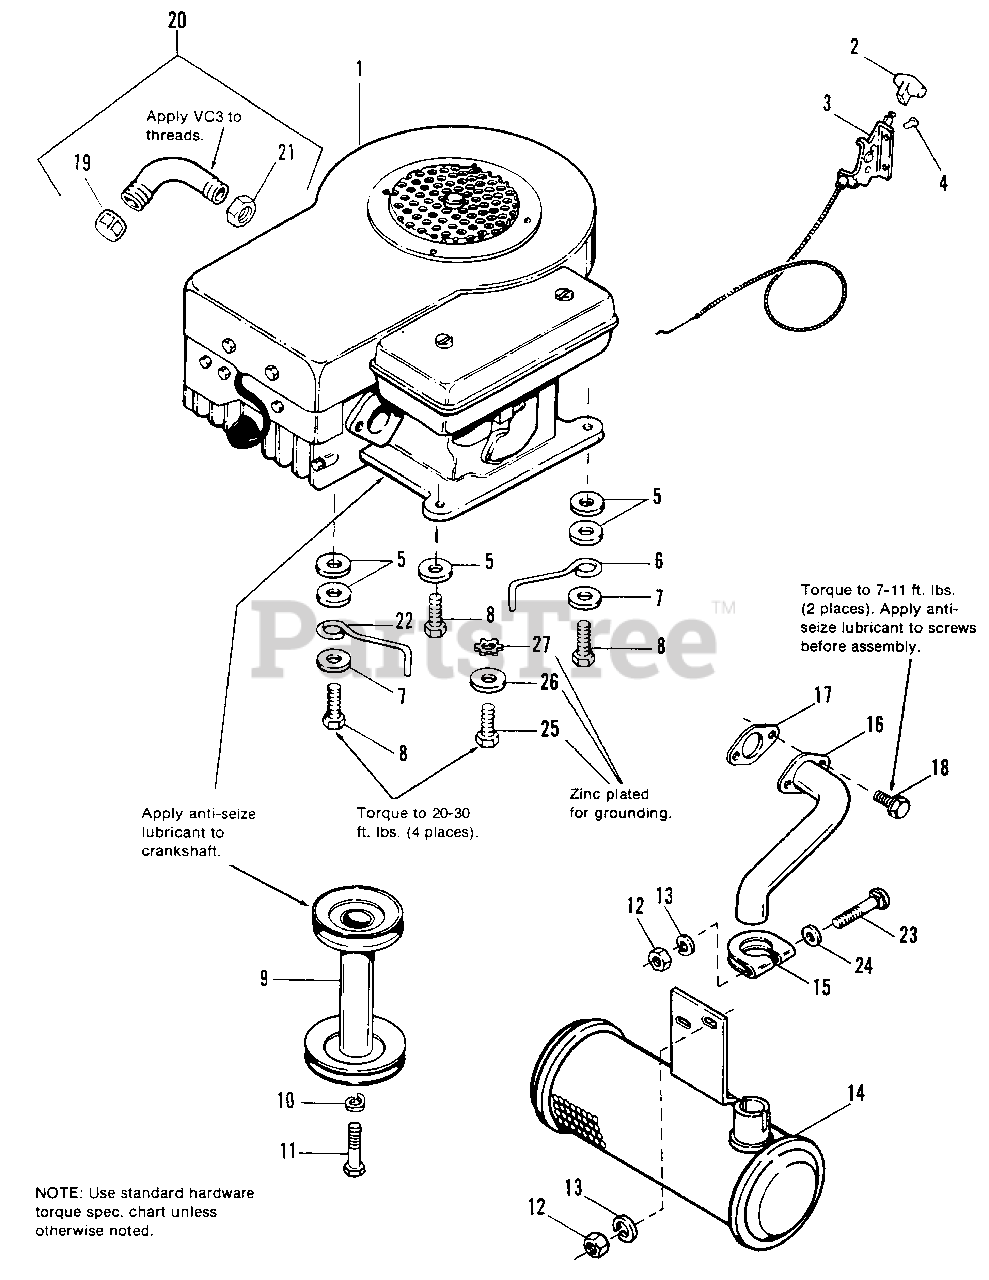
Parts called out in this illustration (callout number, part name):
1	ENGINE, 11 HP, Briggs & Stratton
1	ENGINE, 12 HP, Briggs & Stratton
2	KNOB, Throttle
3	CONTROL ASSY., Throttle
4	RIVET, Pop, 1/4
5	WASHER, Plain, 3/8
7	WASHER, 3/8
8	SCREW. Taptite, 3/8-16 x 1-1/2
9	PULLEY ASSY., Engine
10	LOCKWASHER, 7/16
11	CAPSCREW, Hex, 7/16-20 x 1-1/4
12	NUT, Hex, 5/16-18
13	LOCKWASHER, 5/16
15	CLAMP, Exhaust
16	PIPE, Exhaust
17	GASKET, Muffler
18	SCREW. Whizlock, 5/16-18 x 3/4
19	CAP. Pipe, 3/8
20	PIPE, Oil Drain (Incl. Ref. Nos. 19 & 21)
21	LOCKNUT. Conduit, 3/8
23	BOLT, Carriage, 5/16-18 x 2-3/4
24	WASHER, 5/16
25	SCREW, Taptite, 3/8-16 x 1-1/2 (Zinc Pltd.)
26	WASHER (Zinc Pltd.)
27	LOCKWASHER (Ext. (Zinc Pltd.)
